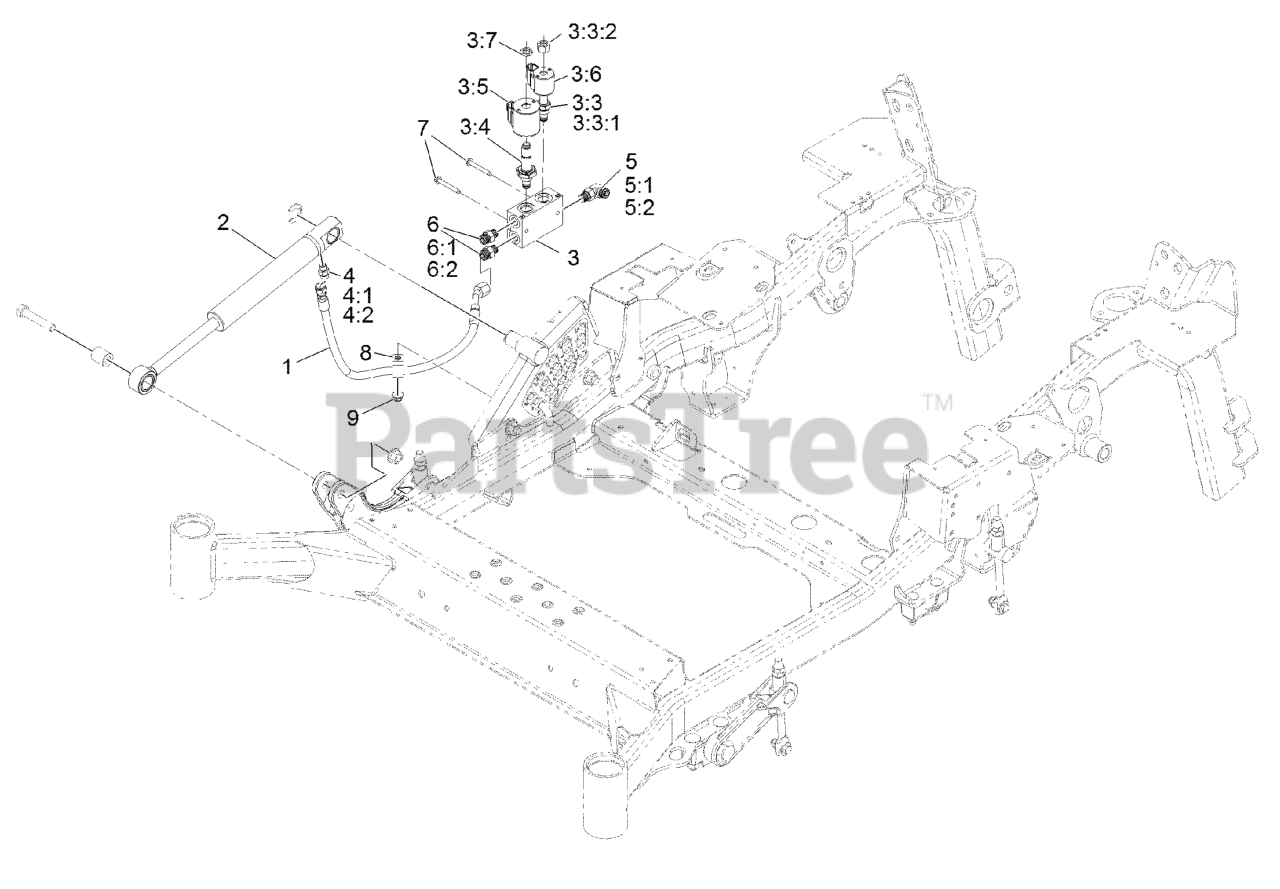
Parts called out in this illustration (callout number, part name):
1	HOSE ASM
2	CYLINDER-LIFT
3	DECK LIFT VALVE ASM
3:3	VALVE-SOLENOID
3:3:1	SEAL KIT
3:3:2	NUT-SOLENOID
3:4	VALVE-SOLENOID
3:5	COIL-12V
3:7	NUT-COIL
4	FITTING-HYD, STRAIGHT
4:1	O-RING
4:2	O-RING
5	FITTING-ELBOW, 90 DEG
5:1	O-RING
5:2	O-RING
6	FITTING-STRAIGHT
6:1	O-RING
6:2	O-RING
7	SCREW-HWHTF
8	CLIP-LOOM
9	NUT-HF, NI
